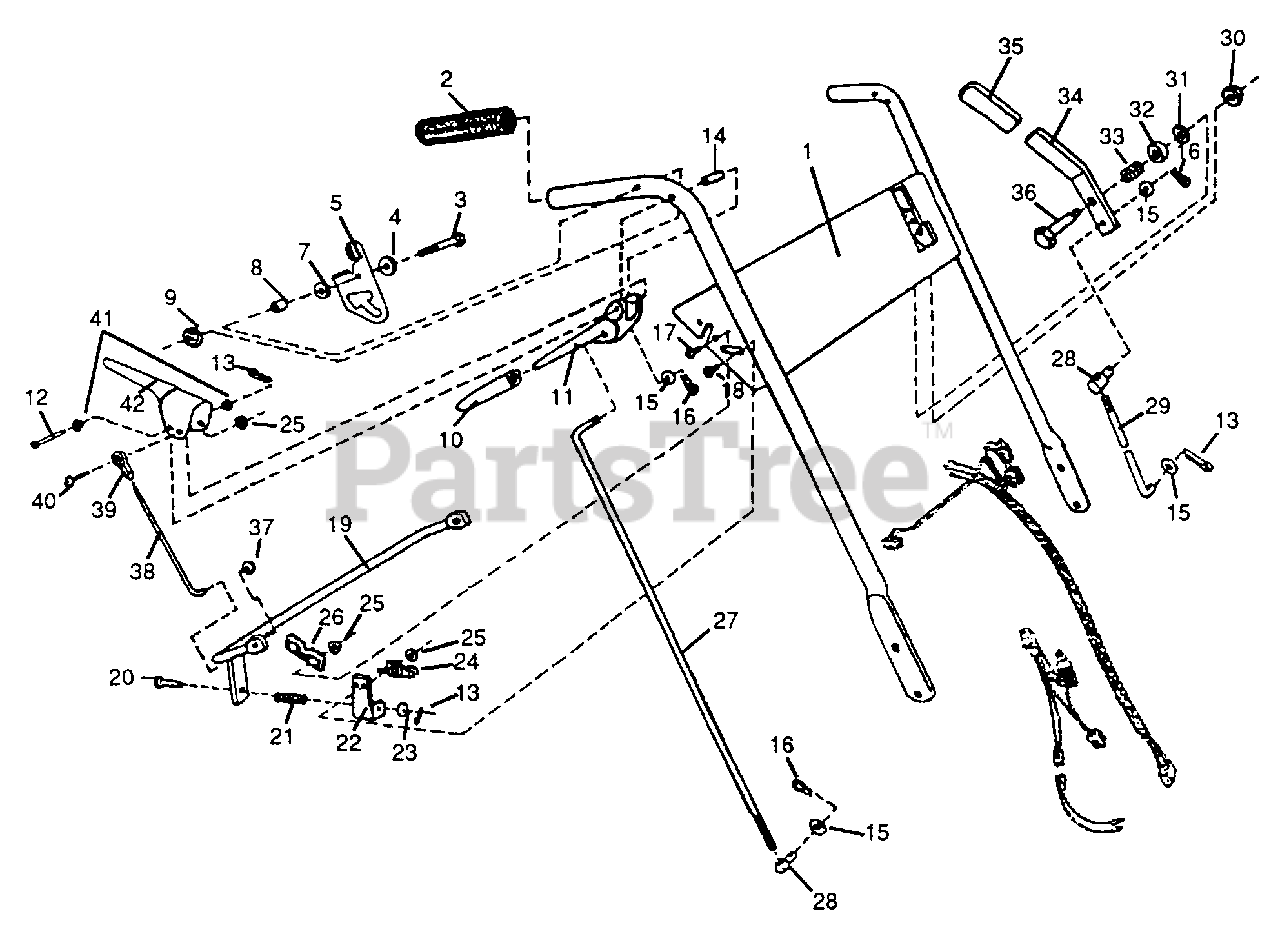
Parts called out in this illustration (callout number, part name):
1	Top Handle w/Decals
2	Handle Grip
3	1/4 - 20 x 2 Hex. Hd. Cap Screw
4	Bellville Washer
5	Traction Thumb Lock, Right
7	1/4 Flat Washer
8	Spacer
9	1/4 - 20 Lock Nut
11	Traction Lever
12	Clevis Pin
13	Cotter Pin
14	Roll Pin
15	5/16' Flat Washer
16	Hair pin
17	10 - 24 x 1/2 Pan Hd. Mach. Saew
18	10 - 24 x 5/8 Rd. Hd. Mach. Screw
19	Presence Bail
20	Clevis Pin
21	Spring
22	Presence Spring Bracket
23	3/16" Flat Washer
24	Presence Switch
25	10 - 24 Lock Washer & Nut
26	Presence Bail Retainer
27	Traction Rod
28	Swivel
29	Blade Control Rod
30	3/8' -16 Flange Nut
31	1/2' Machine Bushing
32	Spacer
33	Spring
34	Blade Engagement Lever
36	Shoulder Bolt
37	Push-On Fastener
38	Link Rod
39	Rod End
40	#10 - 24 x 5/8' Rd. Hd. Mach Screw
41	Bushing, Delrin
42	Presence Lever
